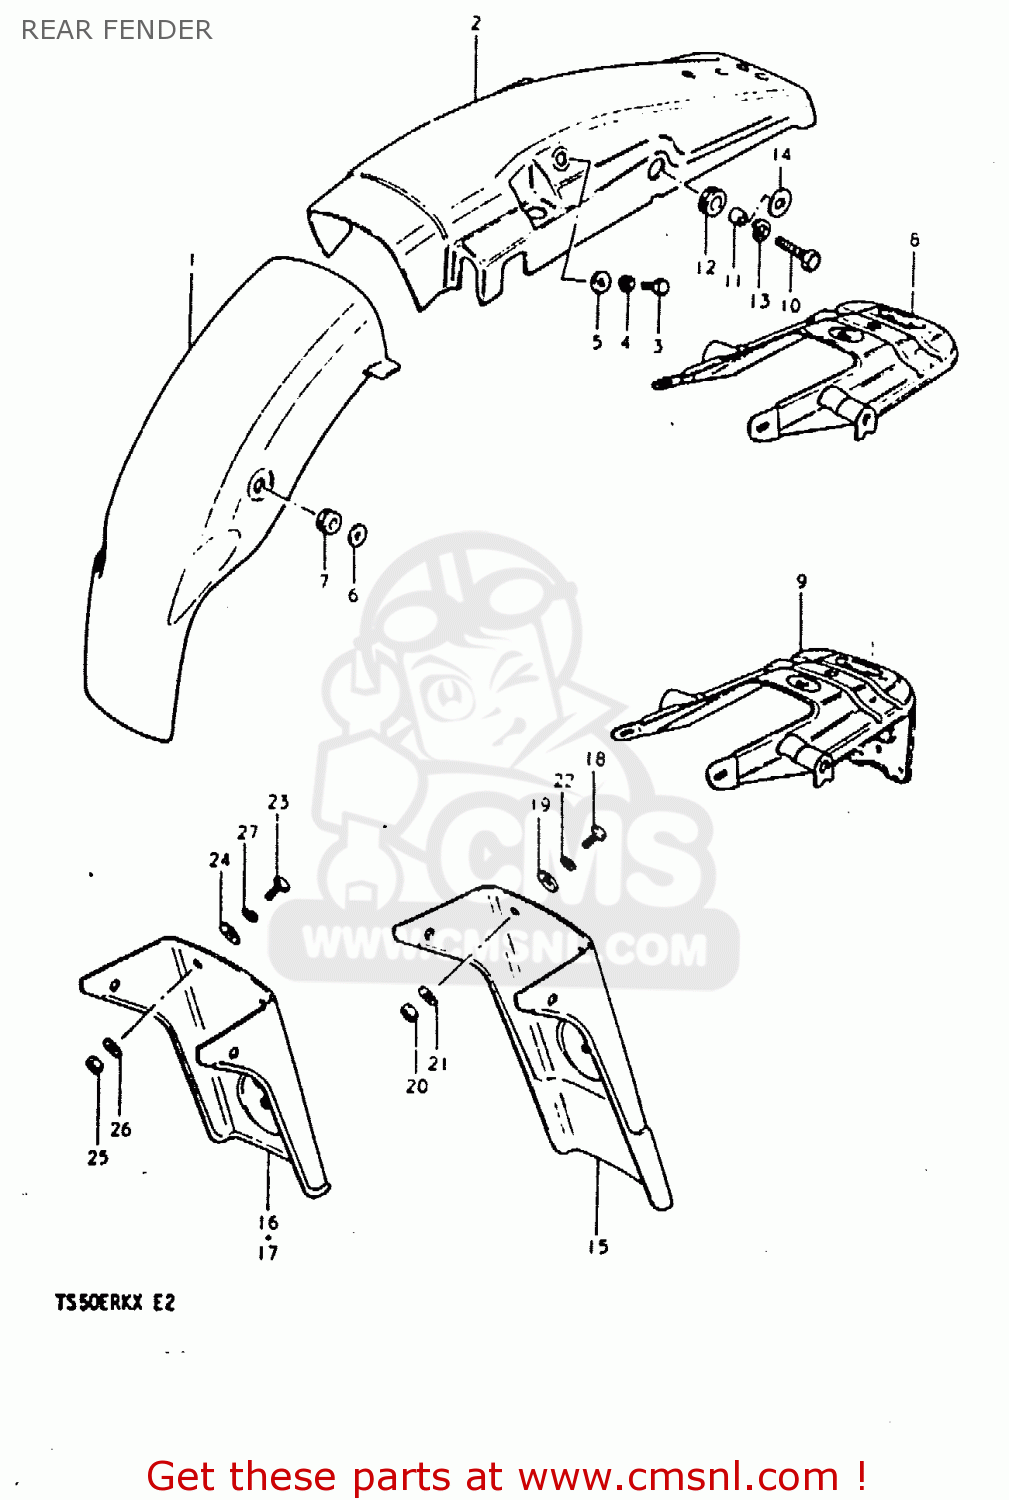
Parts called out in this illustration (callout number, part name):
1	BODY, REAR FENDER FRONT
2	BODY, REAR FENDER REAR
3	BOLT, UPPER
4	LOCK WASHER
5	WASHER
6	WASHER
7	CUSHION
8	REINFORCEMENT
10	BOLT 8X55
11	SPACER (8.2X12X7.5)
12	CUSHION
13	LOCK WASHER
